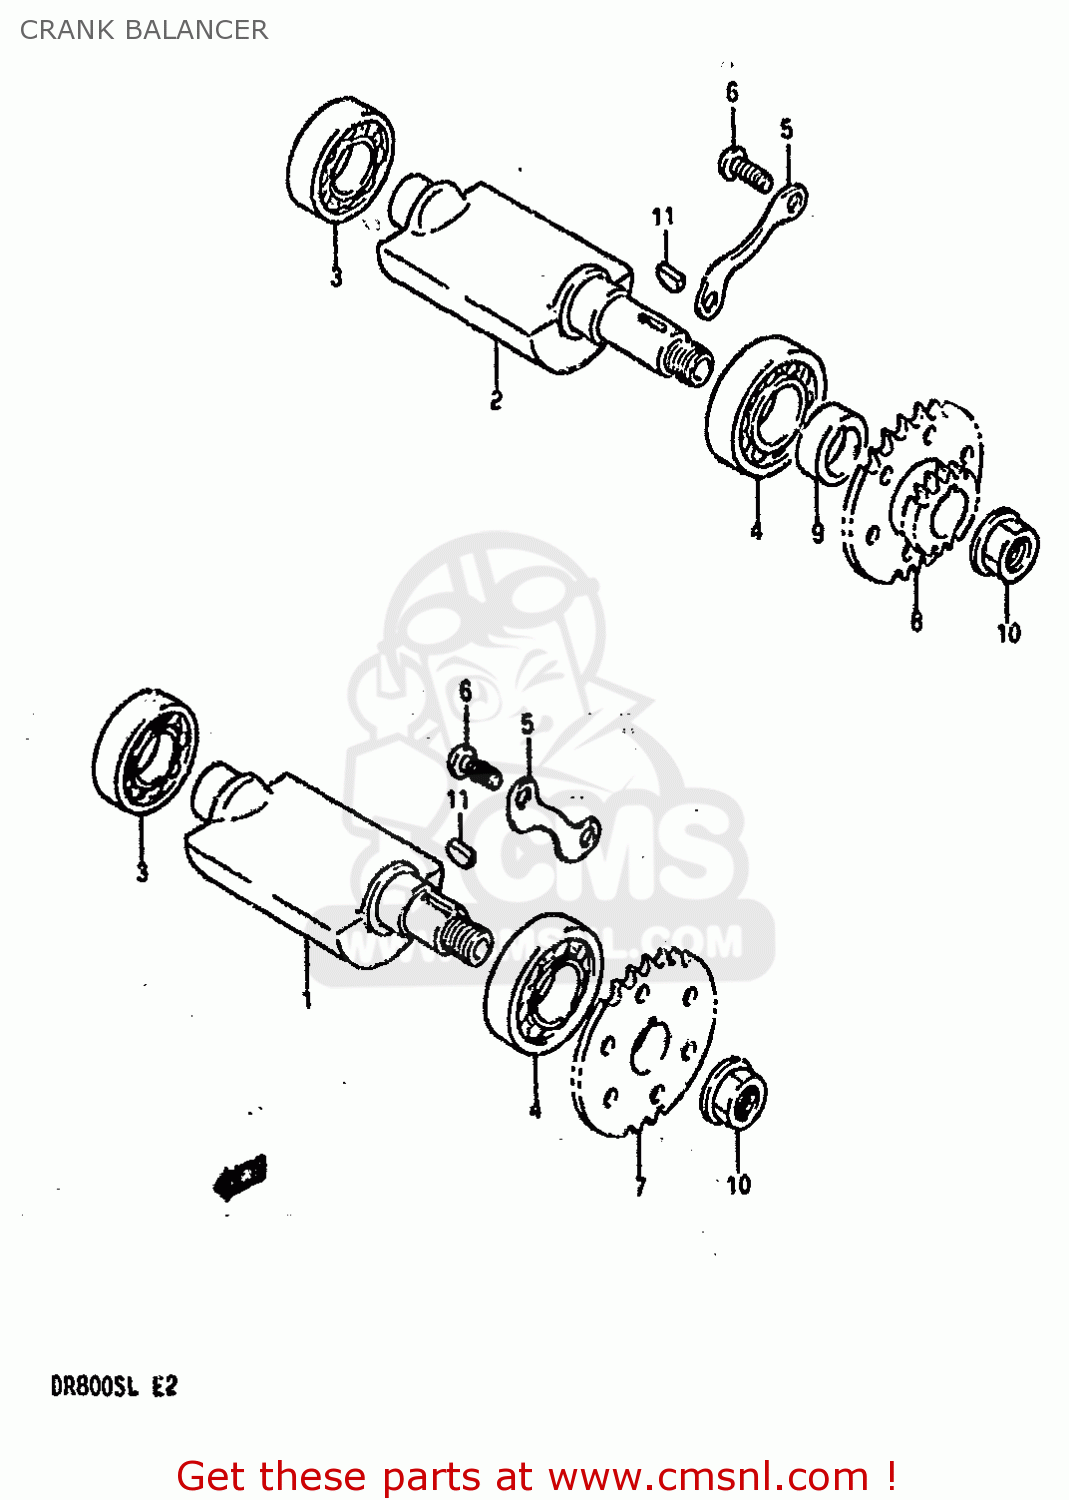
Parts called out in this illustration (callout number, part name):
1	BALANCER,CRANK,FRONT
2	BALANCER,CRANK,REAR
3	BEARING(20X42X12)
4	BEARING(20X47X14)
5	RETAINER,CRANK BAL BEARING
6	SCREW
7	SPROCKET,BALANCER DRIVEN FR
8	SPROCKET,BAL.R
9	SPACER,CRANK BAL RR
10	NUT
11	KEY
